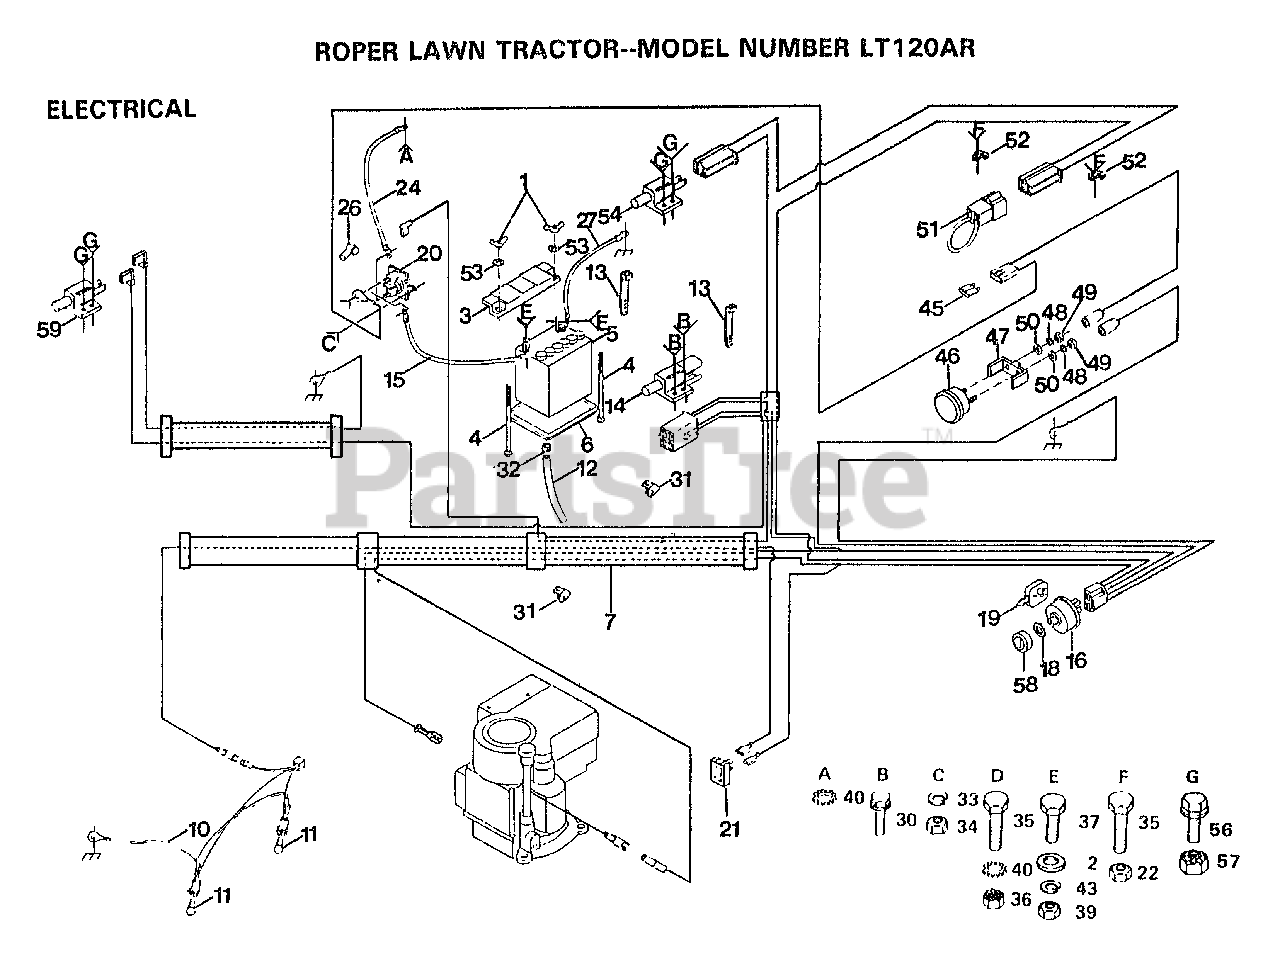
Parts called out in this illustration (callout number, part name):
2	WASHER
4	BOLT
6	"TRAY T, BATTERY"
10	HARNESS T
13	WIRE TIE
14	SWITCH INTERLOCKT
15	"CABLE T, BATTERY"
27	CABLE ASSY LT
31	CLIP-FUEL LINE
32	HOSE CLAMP T
34	NUT
35	BOLT
36	NUT
43	LOCKWASHER
45	FUSE HYT
46	AMMETER T
50	WASHER
52	CLIPT
53	LOCKWASHER GT
54	SWITCH-INTER. GT
55	SWITCH INTERLOCKT
56	SCREW
57	"NUT,KEPS"
59	SWITCH T
